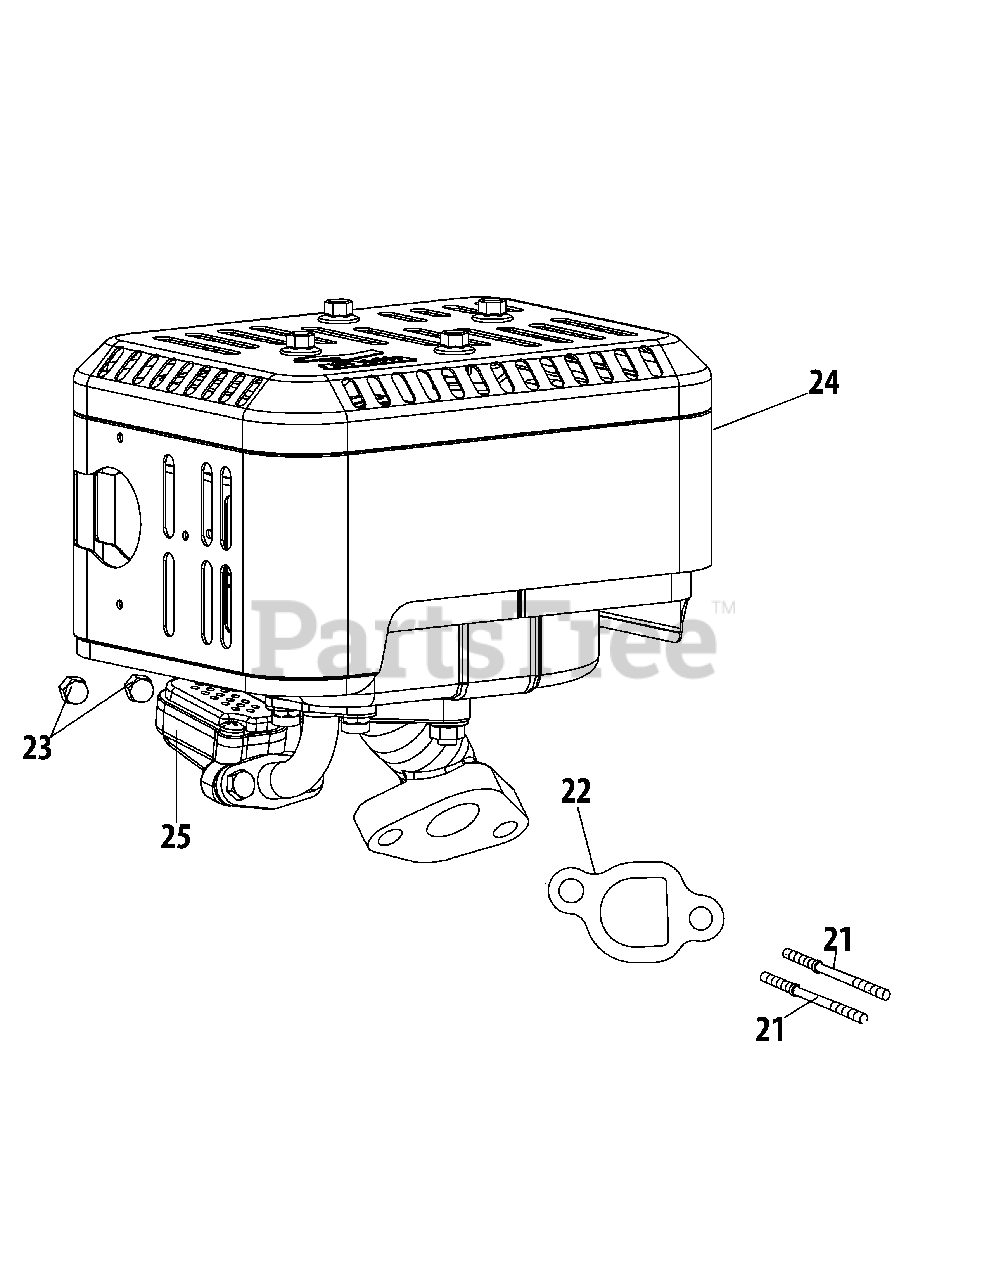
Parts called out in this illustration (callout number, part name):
21	Stud M8×38
22	Exhaust Pipe Gasket
23	Nut, M8
24	Muffler Assembly
25	Secondary Air Valve
